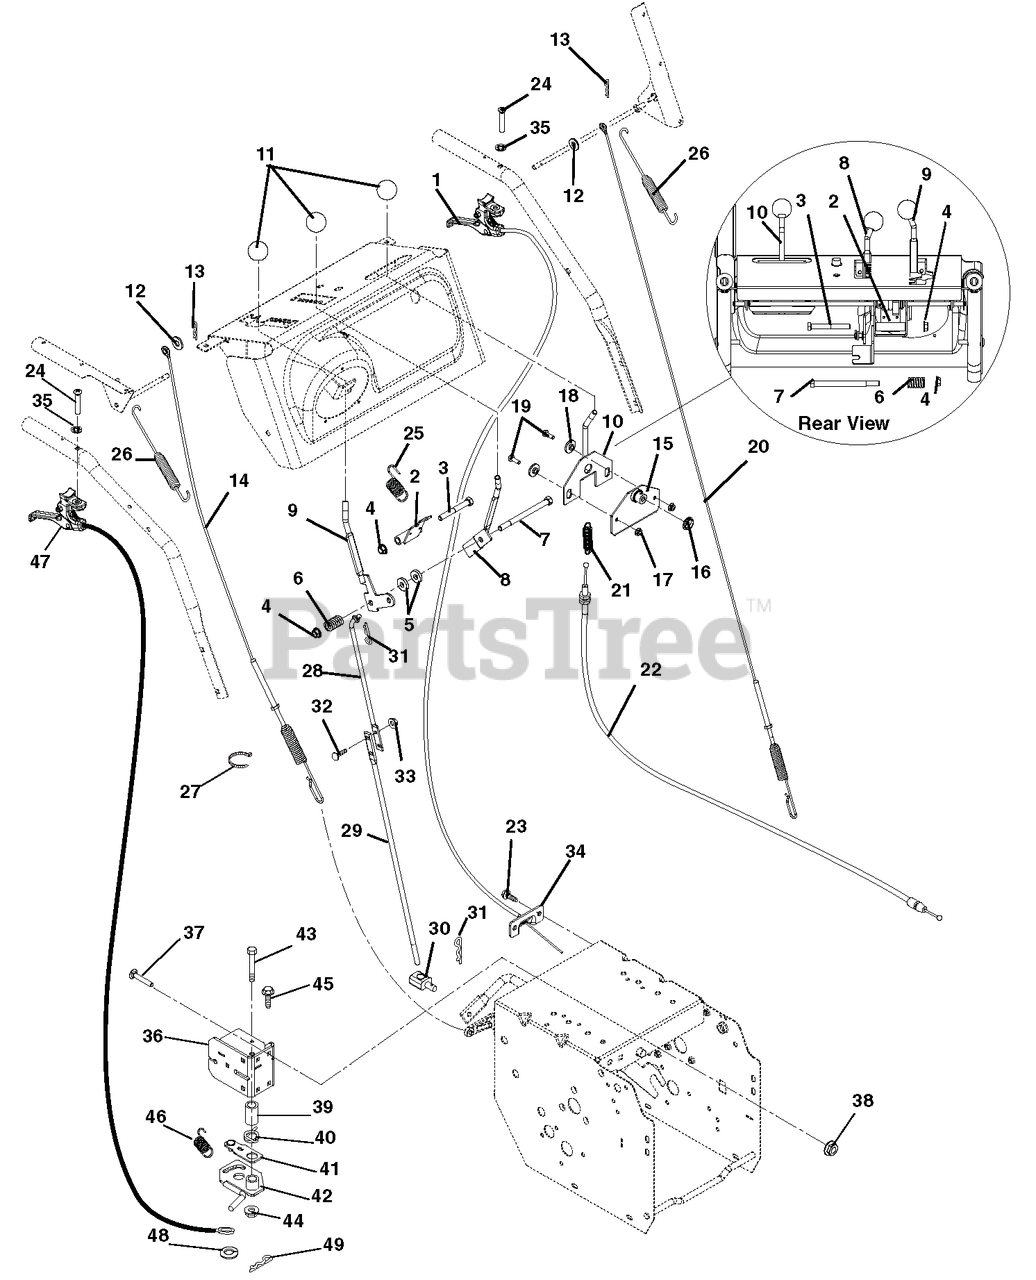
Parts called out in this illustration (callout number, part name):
1	CABLE-TRIGGER-REMOTE WHEEL-DEL
2	ARM, INTERLOCK
3	@BLT-HEX .38-16X3.00 GR5 YWZC
4	@NUT-LK-TOP-FLG .38-16 YWZC
5	WSHR-FL-STL .406X1.00X.188 YWZ
6	SG-COMP .125X.781X1.250
7	@BLT-HEX .38-16X5.00 GR5 YWZC
8	CONTROL, DEFLECTOR
9	LEVER, SHIFT
10	LEVER, CHUTE CONTROL
11	KNOB,BALL -BLACK 1.47" .375-16
12	@WSHR-FL-STL.281X.62X.065 YWZC
13	PIN-HAIR INT .06X.18X.77
14	CABLE, ATTACHMENT
15	MOUNT, CHUTE CONTROL
16	BUSHING, POLYLINER-.75 SNAPIN
17	@NUT-LK-TOP-FLG .25-20 YWZC
18	BSHG-FLG .265X.448X.243X1.00
19	@BLT-HEX .25-20X.75 GR5 YWZC
20	CABLE, TRACTION - DELUXE
21	SG-TENS .048X.44X1.75 WLD 9
22	CABLE, CHUTE LOCK
23	SCR-TAP .25-20X.50 HWH TR YWZ
24	SCR-MCH .25-20X1.50 OVAL HD
26	SG-TENS .056X.60X4.40
27	CABLE TIE LG 5-1/2
28	ROD, SHIFT-UPPER
29	ROD, SHIFT-LOWER
30	PIVOT,SHIFT ROD .375-16(TRUNN)
31	PIN-HAIR, ENDRIES #25 YWZC
32	@BLT-RDHDSQNK .25-20X.75 G5YZ
33	@NUT-LK-TOP-FLG .25-20 YWZC
34	BRACKET, CABLE MOUNT
35	WSHR-LK-INT .250 TH TYA
36	BRACKET, HEIGHT ADJUSTER
37	@BLT-RDHDSQNK .25-20X.75 G5YZ
38	@NUT-LK-TOP-FLG .25-20 YWZC
39	BSHG-SLV .385X.500X1.045
40	SG-TORS .067X.88
41	ARM, OVERTRAVEL
42	LOCK, HEIGHT ADJUSTER
43	@BLT-HEX .38-16X1.75 GR5 YWZC
44	NUT-LK-CTR-FLG .38-16 YWZC
45	SCR-TAP .25-20X.50 HWH TR YWZ
46	SPRING-EXT .047 X .438 X 1.85
47	CABLE, TRACK REMOTE
48	@WSHR-FL-STL.281X.62X.065 YWZC
49	PIN-HAIR INT .06X.18X.77
